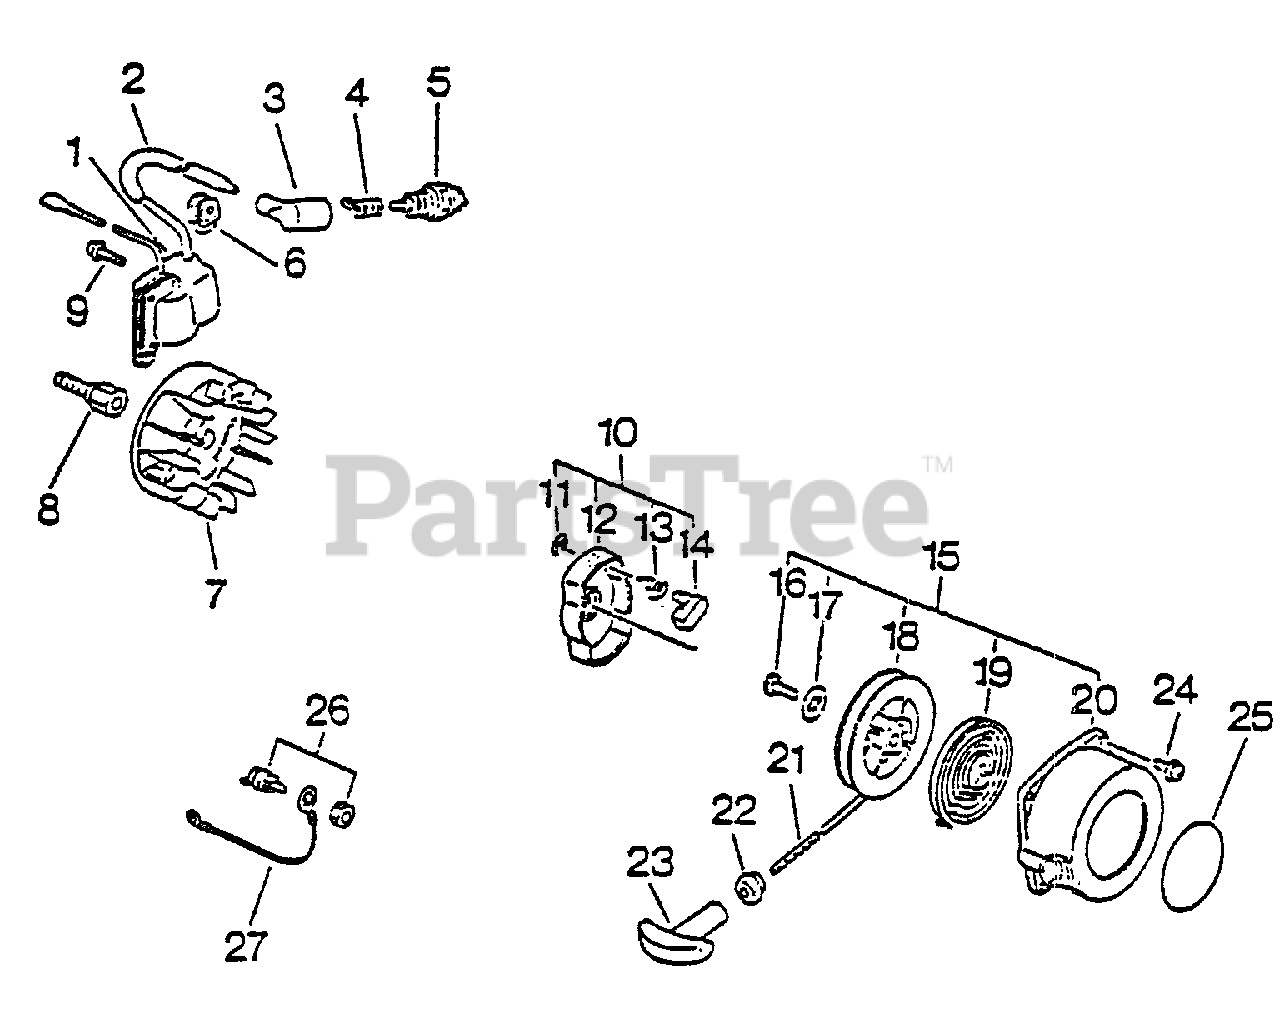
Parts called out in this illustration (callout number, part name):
1	COIL, IGNITION
3	CAP, SPARK PLUG
4	TERMINAL, SPARK PLUG CAP
5	SPARK PLUG -- BPM-7A
5	SPARK PLUG -- BPMR-7A
7	FLYWHEEL
8	HUB, FAN
9	SCREW - 4X22
10	STARTER PAWL ASSY
11	RING, RETAINING - 4
12	CATCHER, PAWL
13	SPRING, RETURN
14	PAWL, STARTER
15	STARTER ASSY
17	WASHER
18	REEL, ROPE
19	SPRING, REWIND
20	CASE, STARTER
21	ROPE, STARTER - 3X890
22	GUIDE, ROPE
23	GRIP, STARTER
24	SCREW - 4X18
25	LABEL - ECHO
26	IGNITION SWITCH ASSY
27	LEAD - GROUND
